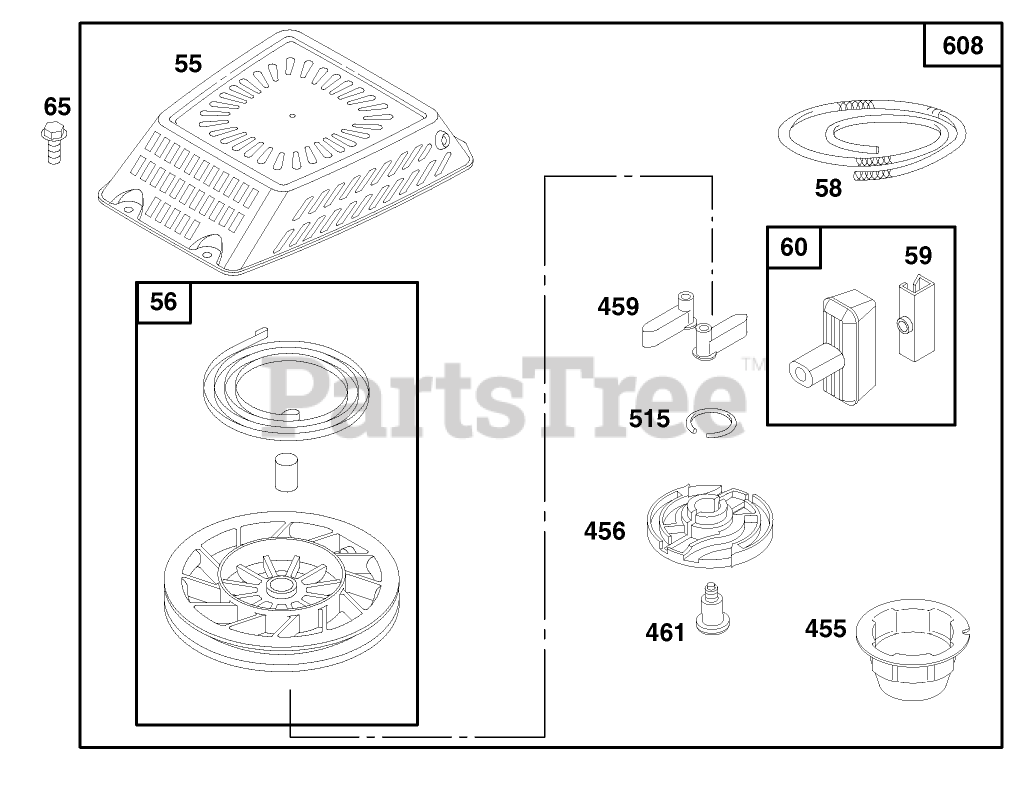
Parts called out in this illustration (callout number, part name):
56	PULLEY-STARTER, REWIND
58	ROPE-STARTER
59	INSERT-HANDLE, REWIND
455	CUP - STARTER
456	RETAINER-STARTER, REWIND
459	PAWL-STARTER
515	SPRING-TORSION
608	BRIGGS 498147
